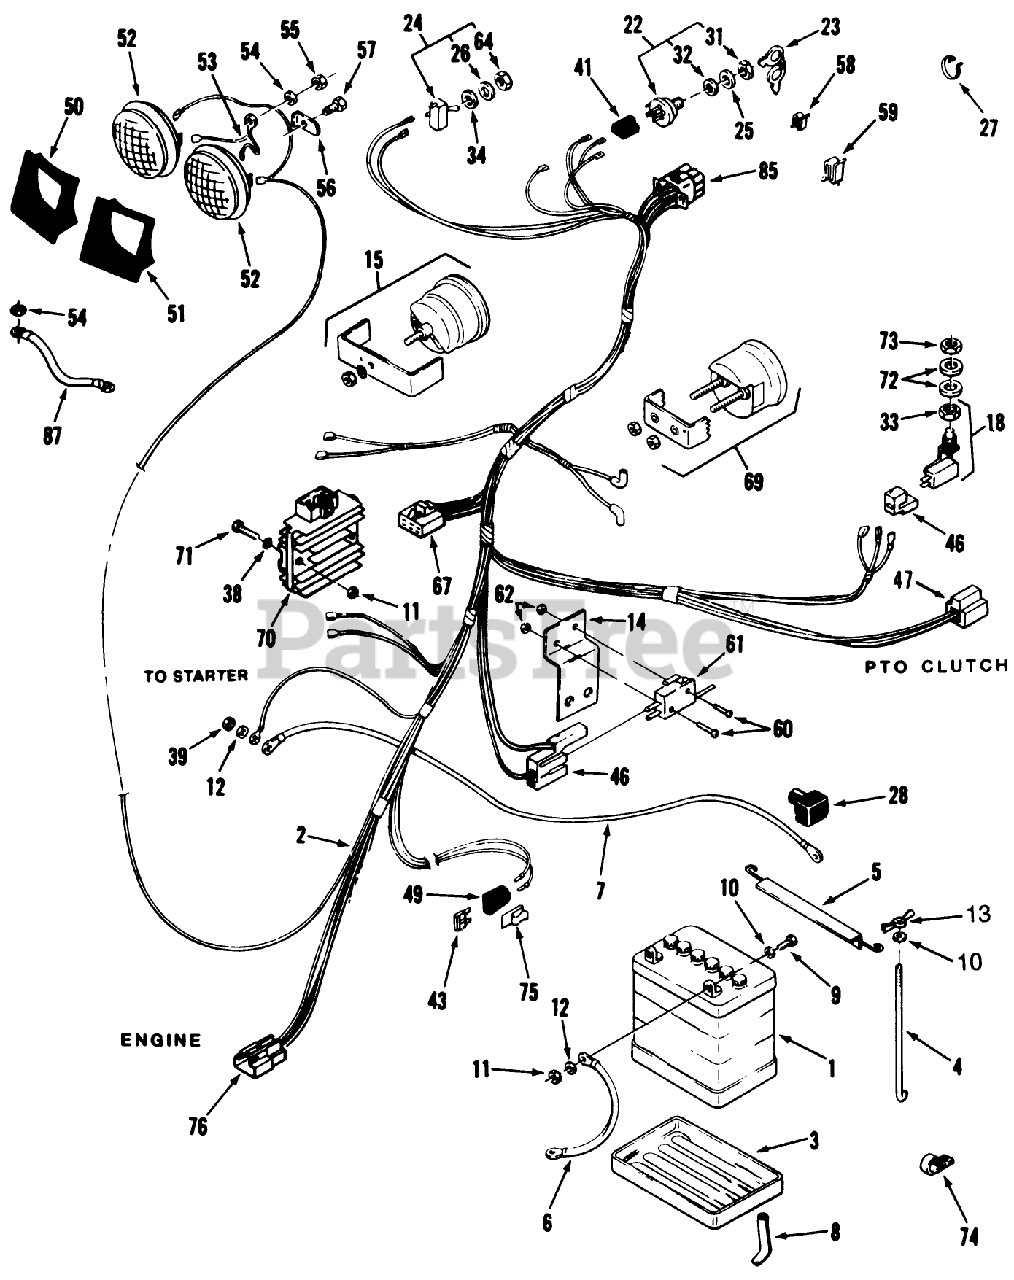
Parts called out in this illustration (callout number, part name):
1	Battery
2	MAIN-HARN & WIRE DIA
3	TRAY-BATTERY
5	HOLDDOWN-BATTERY
6	WIRE - 14" BLACK
7	ASSY WIRE
8	TUBE-21" BATTERY DRAIN
9	SCREW-HH
10	WASHER-FLAT
11	Nut
12	WASHER-LOCK
13	NUT-WING
14	BRKT SWITCH BRAKE R
15	Hourmeter (includes 114017 Gauge Mtg. Bracket, 915962 Keps Nuts 2])
18	Seat Switch
22	Ignition Switch (includes items 31 & 32)
23	Ignition Key
24	Light Switch (includes items 33 & 34)
25	Washer
26	Washer
27	PLASTIC TIE
28	Boot
32	LOCKWASHER
38	WASHER-LOCK/EXT
39	NUT-LOCK
41	CONNECTOR-5 WAY-SERV
43	FUSE-BLADE, 15 AMP
46	CONNECTOR BODY
47	CONNECTOR BODY
49	FUSE-BLOCK ASS'Y
50	BEZEL-HEADLIGHT, RH
51	BEZEL-HEADLIGHT, LH
52	HEADLAMP
53	LIGHT GROUND WIRE
54	WASHER-LOCK, INTERNAL
55	NUT-HEX
56	LOCK-HEADLIGHT
57	Bolt
58	CLIP
59	SPEED CLIP
60	Screw
61	SWITCH - CLUTCH
62	NUT HEX 4-40 ELAST
67	CONNECTOR BODY
69	Voltmeter (Includes 109650 Clamp & 5924 = 10-32 Nut)
70	Voltage Regulator 257-H (Kawasaki #21066-2056)
71	HHCS 1/4-20X1" WHIZ
72	Washer
73	NUT-HEX SPECIAL
74	CLAMP
75	MOUNTING-CLIP CONN
76	3-CONTACT LOCK-TYPE
85	9-Terminal Connector
87	WIRE-LIGHT GROUND
